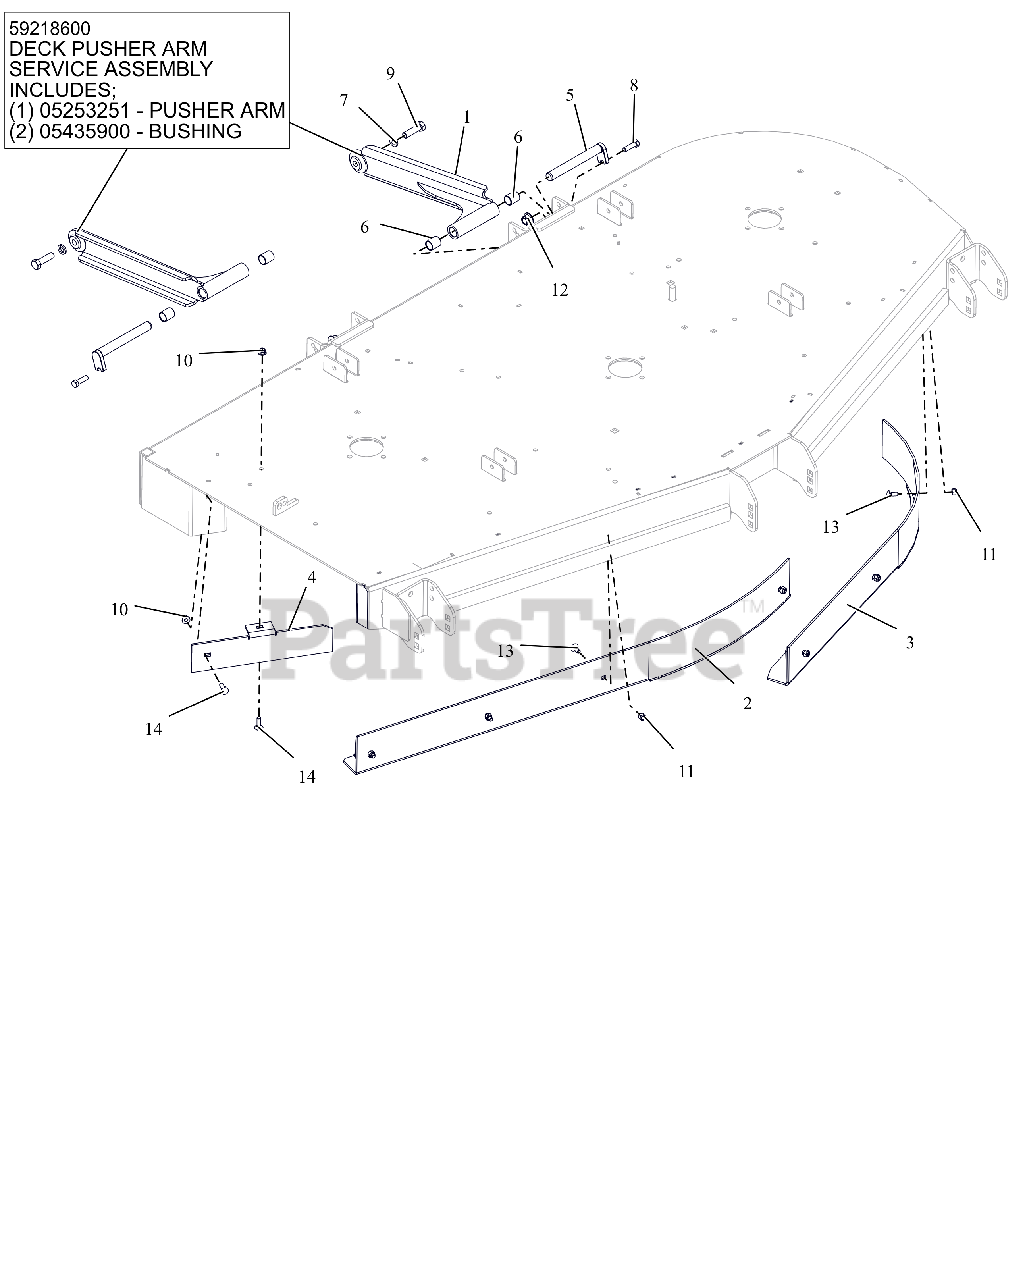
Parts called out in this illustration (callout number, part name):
1	WLDMT, DECK STABILIZER ARM (BLACK)
1	DECK STABILIZER ARM W/BUSHINGS
2	WLDMT, 72" RH VACUUM BAFFLE (RED)
3	WLDMT, 72" LH VACUUM BAFFLE (RED)
4	72" DISCHARGE BAFFLE - RED
5	PIN, MOWER MTG
6	BRG, .750 X .875 X 1.000
7	WSHR,LK-REG .500X.125 ZCC
8	BLT, HEX .38-16X1.25 G5 ZCC
9	BLT, HEX 0.5-13X1.75 GR5 ZCC EP80
10	NUT,NYL-FLG .31-18 GF ZCC
11	NUT,NYL .31-18 G5 ZCC
12	NUT,NYL-FLG .50-13 GF ZCC
13	BLT,RHSN .31-18X.75 G5 ZCC
14	BLT,RHSN .31-18X1.00 G5 ZCC
